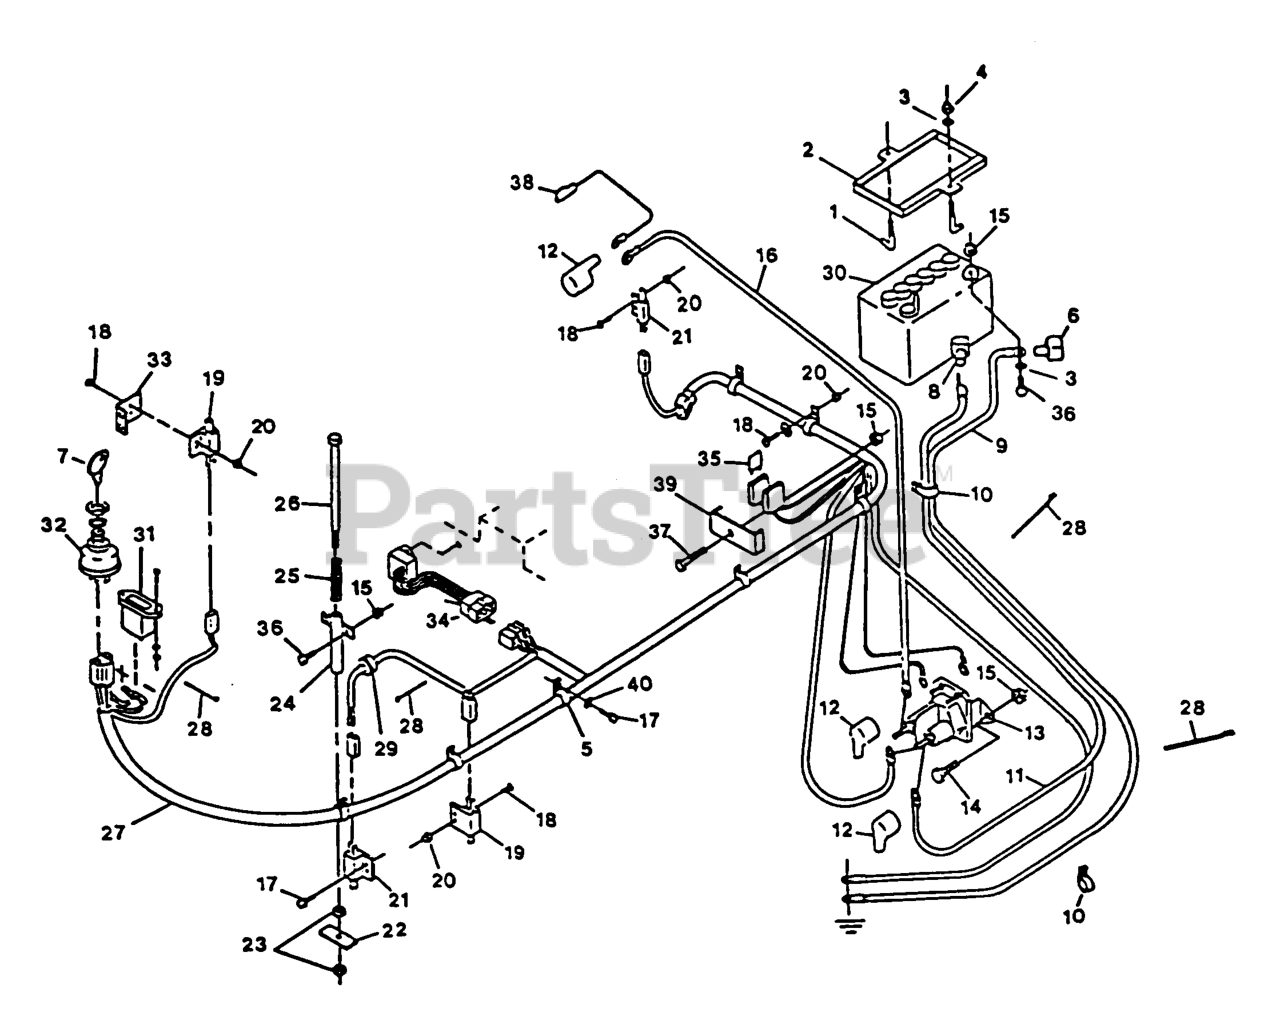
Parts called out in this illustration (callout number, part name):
1	BOLT,HOLDDOWN
2	WLD,HOLDDOWN BATTERY
5	CLIP-LOOM
6	INSULATOR, BATTERY -
7	KEYS-IGNITION (SPARE PAIR
10	CLIP-LOOM
12	INSULATOR-SOLENOID
19	SWITCH-OPEN, NORMALLY
21	SWITCH-CLOSED, NORMALLY
22	PLATE-SWITCH, SEAT
24	MOUNT-SPRING, SEAT
25	SPRING-SWITCH, SEAT
26	SCREW-HH
27	WIRHRNS,EXPLORER
28	TIE-CABLE
29	GROMMET,.38 HOLE
31	METER-HOUR
32	SWITCH,IGNITION
33	BRACKET,PTO SWITCH MOUNT
34	MODULE,OPC
35	FUSE-BLADE TYPE, 20 AMP
39	CLIP-FUSE BLOCK PLTD
